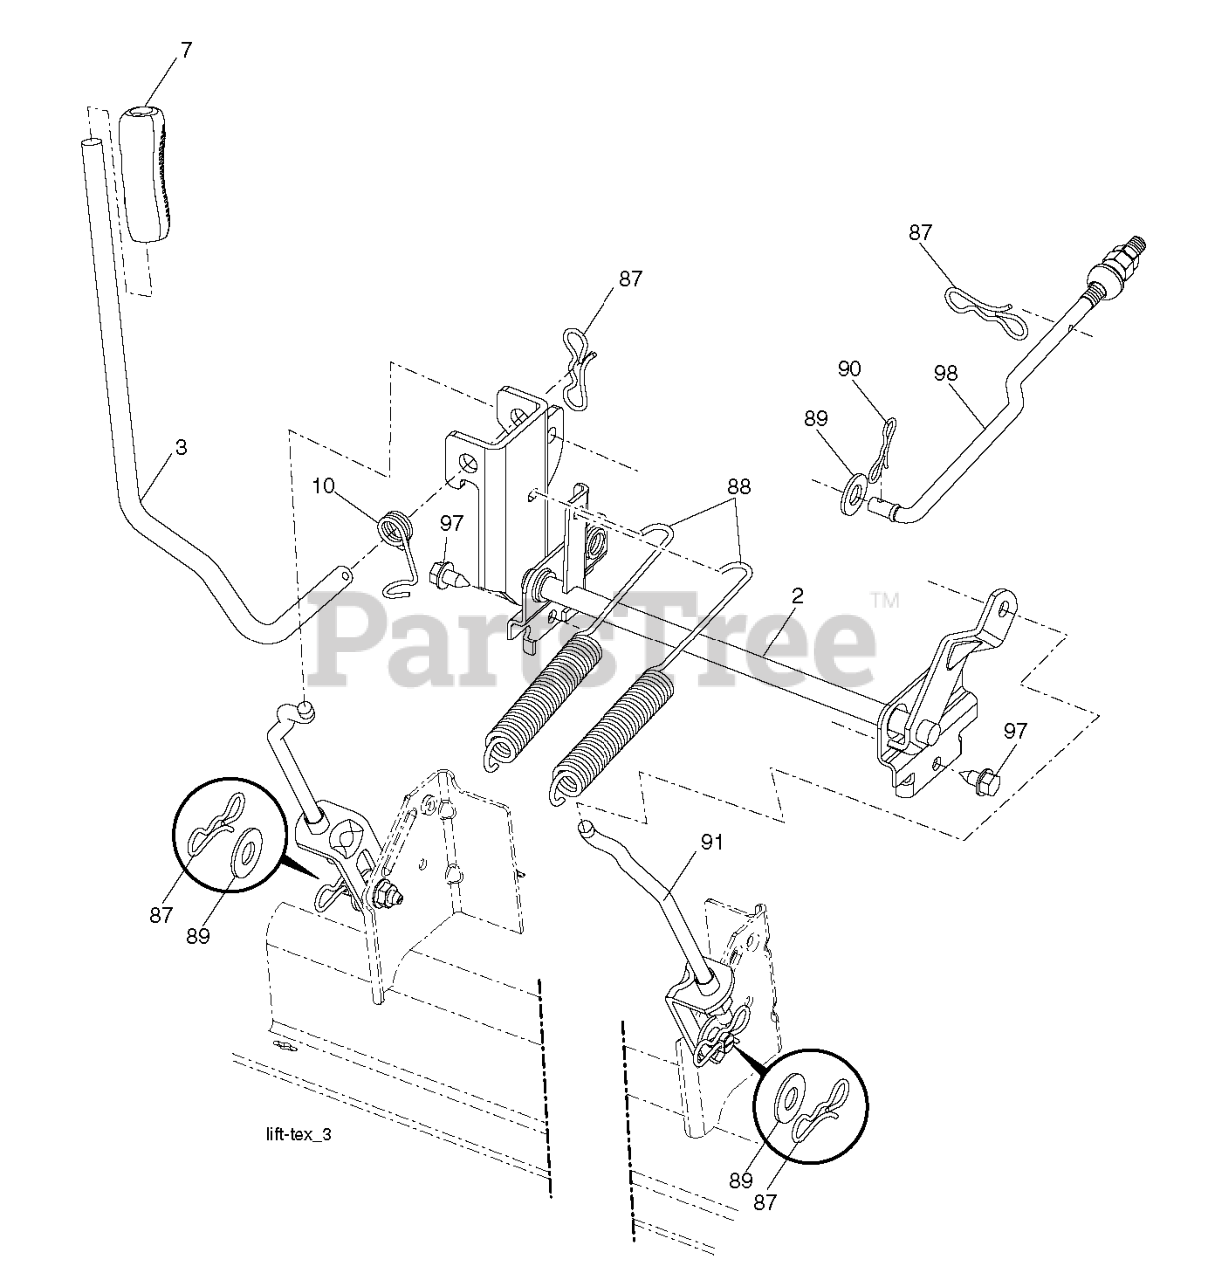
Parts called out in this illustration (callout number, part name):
2	SHAFT.ASM.CROSS.LIFT
3	LEVER.LIFT.HANDLE.GT
7	GRIP.HANDLE.LIFT.PVC.BLACK
10	SPRING.TORSION.LIFT.HANDLE
87	PIN.COTTER.7/16.BOW TI.
88	SPRING.LIFT.ASSIST.GT2
89	WASHER.CLEAR.ZINC
90	PIN.COTTER.5/16.BOW TI
91	LINK.ASM.LIFT.54"TG
97	SCREW, 3/8-16X3/4
98	LINK.ASM.SUSP.FRONT.MWR.10.5
